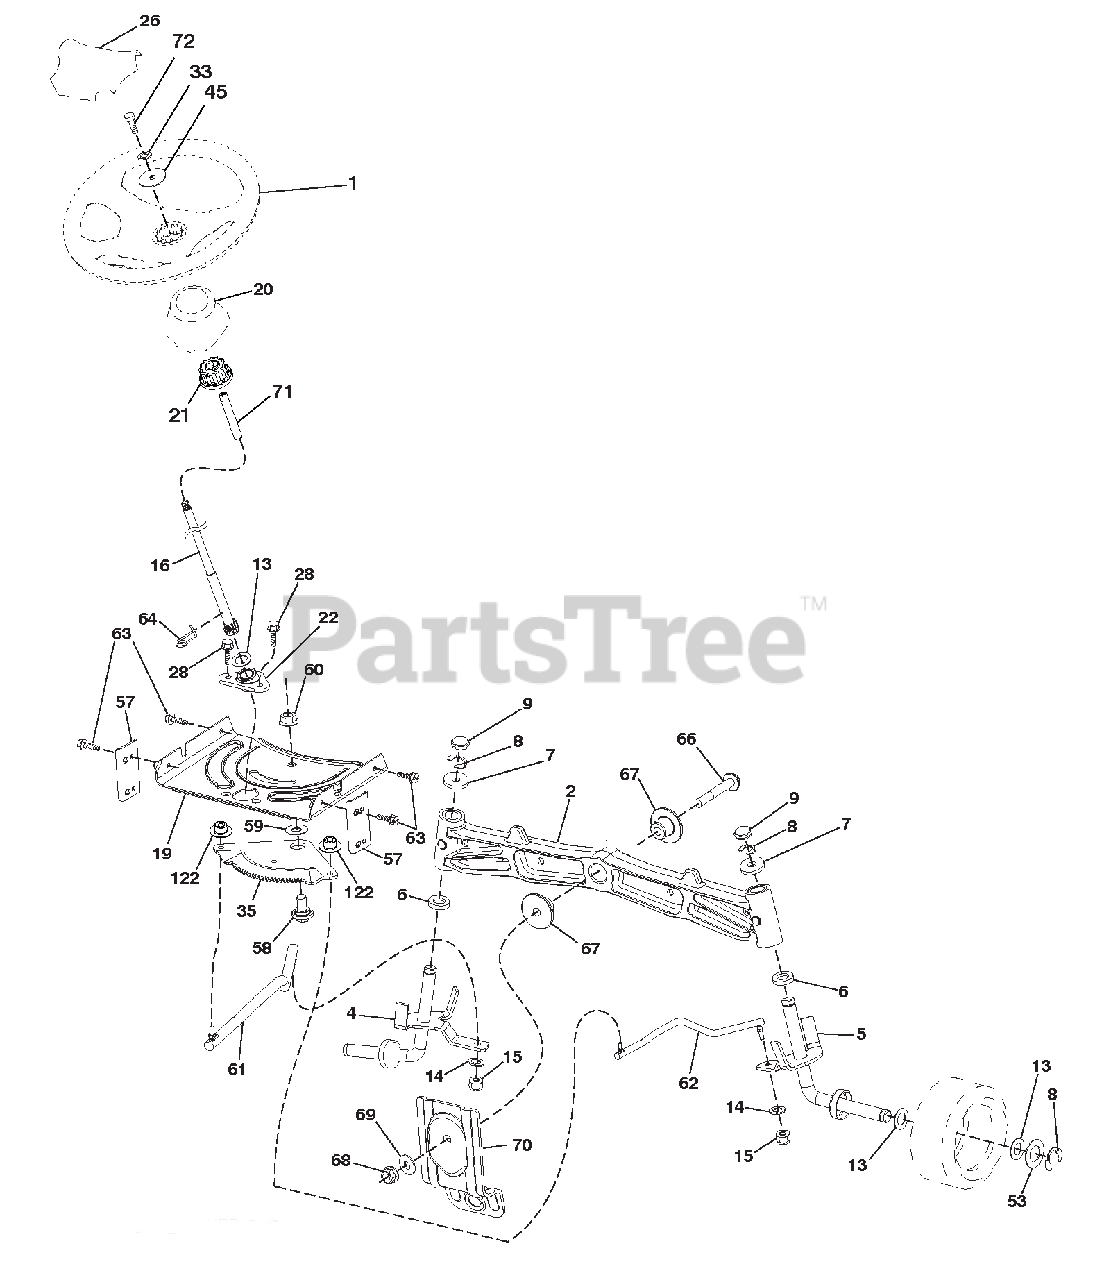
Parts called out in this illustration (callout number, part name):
1	WHEEL.STEERING.HARD RIM.BLACK
2	AXLE.CAST IRON
4	SPINDLE.WELDED.LH.15"TEX
5	SPINDLE.WELDED.RH.15"TEX
6	WAHSER THRUST .75 X 1.230
7	WASHER.25/32 X 1-5/8 X 16GA.
8	RING.KLIP.#T5304-75
9	CAP.SPINDLE.FR.TOP.BLK.
13	WASHER.25/32 X 1 1/4 X 16 GA.
14	Washer, Lock 3/8
15	NUT.CROWNLOCK.3/8-24
16	SHAFT.STEER.3/4 TEX.NON-PLATED
19	PLATE.STEER.DDL.NLT/NGT
20	BOOT.STEERING
21	ADAPTER.WHEEL.STRG..760
22	STEERING SUPT.LOWER
26	CAP WHEEL STEERING HRS/SRS BLK
28	SCREW.HEXWSH THDR3/8-16X3/4.BL
33	Washer, Lock 5/16
35	GEAR SECTOR.PLATE.DDL.NLT/NGT
45	WASHER.11/32ID X2 3/8OD X 12GA
53	WASHER.HARDEN..793 X 1.637X060
57	BRACKET.UPSTOP.TEX
58	BOLT.SHOULDER.SECTOR.PIVOT.CFM
59	WASHER.THRUST.SECTOR.STEER.NLT
60	NUT.FLANGE LOCK.5/8-11
61	DRAGLINK.LH.BALLSTUD.DDL.
62	DRAGLINK.RH.BALLSTUD.DDL
63	SCREW.5/16-18X3/4.SMGML.TAP/BL
64	RETAINER.CLIP.SPRING.STEERING
66	BOLT.HEX.FGHD.7/16-14 X 3.SERR
67	BUSHING.PM.FRONT AXLE
68	NUT.LOCK.FLANGE.7/16-14.GR5
69	WASHER.1.5 X .505 X .118
70	BRACKET.DECK.SUSPENSION.FRONT
71	Extension Steering
72	Bolt 5/16-18 x 14 w/Patch
122	CAP GEAR SECTOR
